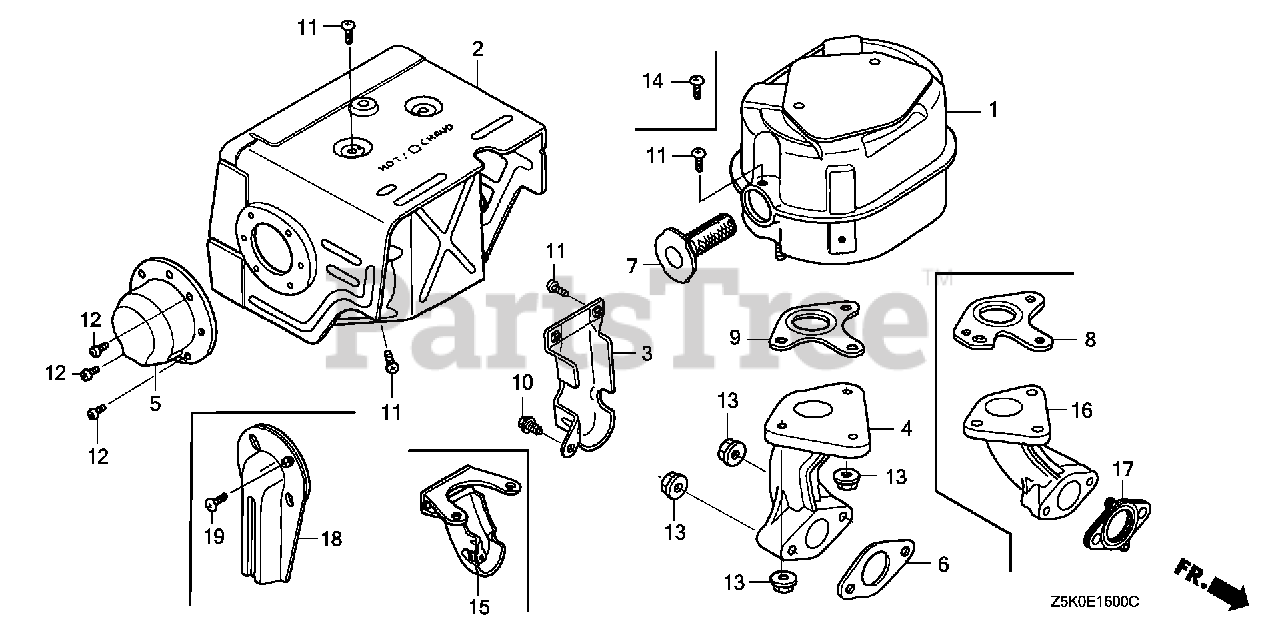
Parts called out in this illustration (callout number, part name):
7	ARRESTER, SPARK
8	GASKET, MUFFLER (ARRESTER)
14	SCREW, TAPPING (4X6) (TO INSTALL OPTIONAL SPARK ARRESTER)
